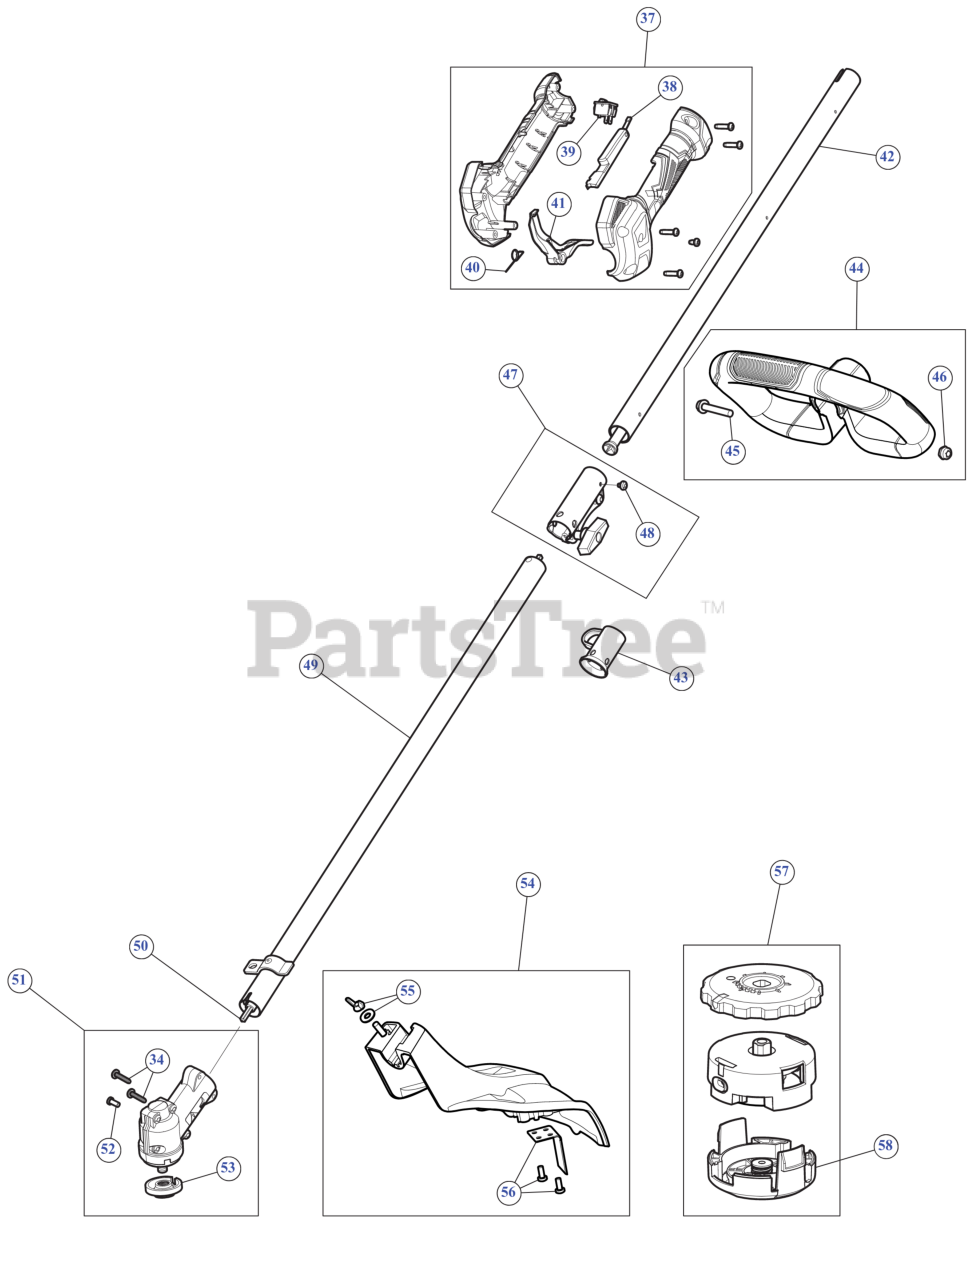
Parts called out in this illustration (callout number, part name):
37	THROTTLE GRIP ASSEMBLY
38	THROTTLE LOCK LEVER
39	SW, MOMENTARY ON/O
40	TRIGGER SPRING
41	THROTTLE TRIGGER
42	BOOM ASSEMBLY UPR
43	HANGER
44	D HANDLE
45	BOLT 1/4-20X1 1/2
46	NUT 1/4-20 NYLOC
47	COUPLER ASSEMBLY
48	SCREW, 10-32X.250 TA
49	LOWER BOOM ASSEMBLY
50	LOWER DRIVE SHAFT
51	GEARBOX LCBC
52	SCREW, 8-32 x .312 P
53	CUTTING HEAD SPACER
54	GUARD/BLADE ASSEMBLY
55	BLADE GUARD MOUNTING HARDWARE
56	BLADE ASSEMBLY W/HDW
57	CUTTING HEAD
